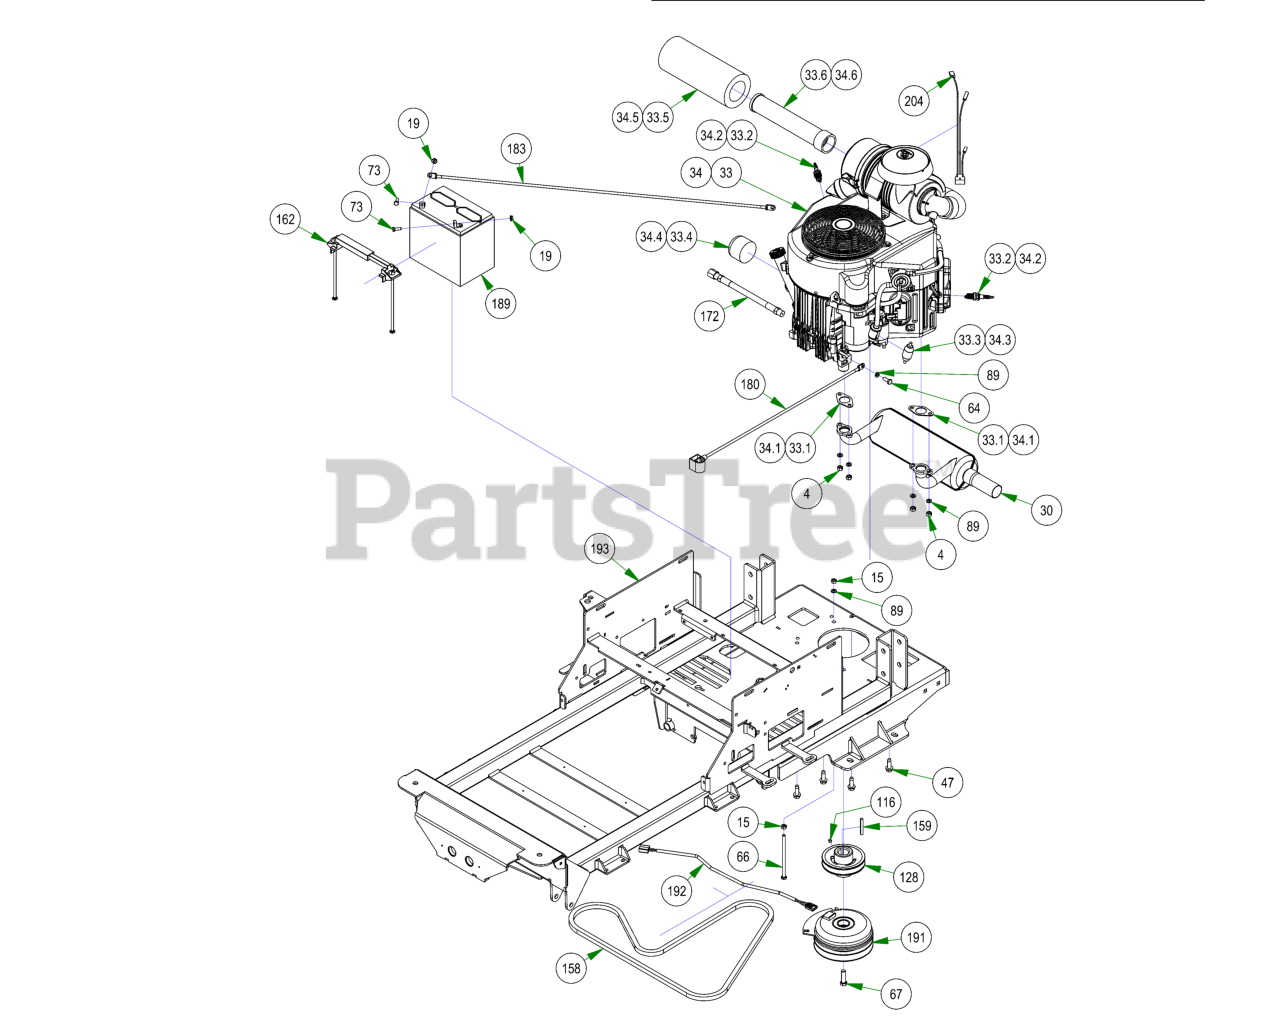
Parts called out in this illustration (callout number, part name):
4	M8-1.25 DIN 934 HEX NUT (CL.8) ZINC
15	5/16-18 HEX NUT ZINC
19	1/4-20 HEX SERRATED FLANGE NUT HARD/ZINC
30	Kawasaki Muffler 1251
33	FX691 Kawasaki-2016 Compact Outlaw
33.1	Exhaust Gasket
33.2	Spark Plug - Kawasaki
33.3	Universal Inline Fuel Filter
33.4	Oil Filter
33.5	Canister Air Filter- Outer
33.6	Canister Air Filter- Inner
34	FX-730 Kawasaki
34.1	Exhaust Gasket
34.2	Spark Plug - Kawasaki
34.3	Universal Inline Fuel Filter
34.4	Oil Filter
34.5	Canister Air Filter- Outer
34.6	Canister Air Filter- Inner
47	3/8-16 X 1-1/8 HEX WASHER UNSLOT SERRATED (TRI-LOB) TRS ZINC YELLOW
64	M8-1.25 X 20MM DIN 933 HEX TAP BOLT (CL 8.8) ZINC
66	5/16-18 X 5-1/2 HEX CAP SCREW (GR.5) ZINC
67	7/16-20 X 1-1/2 HEX CAP SCREW (GR.8) w/ Patch
73	1/4-20 X 3/4 HEX CAP SCREW (GR.5) ZINC
89	5/16 SPLIT LOCKWASHER ZINC
116	5/16-24 X 1/4 SOCKET SET SCREW (CUP PT) PLAIN
128	4 3/4 Motor Pulley
158	75.8" Pump Belt
159	1/4 X 2 SQ MACHINERY KEY 1018 STL PLAIN
162	Hold Down Assembly
172	Oil drain Hose
180	24 inch Black Cable – MZ/ZT
183	36" Red Battery Cable
189	SP-35 Battery
191	Clutch Assembly
192	Clutch Pigtail
193	2022 Maverick Frame - Painted
204	Harness Adaptor
